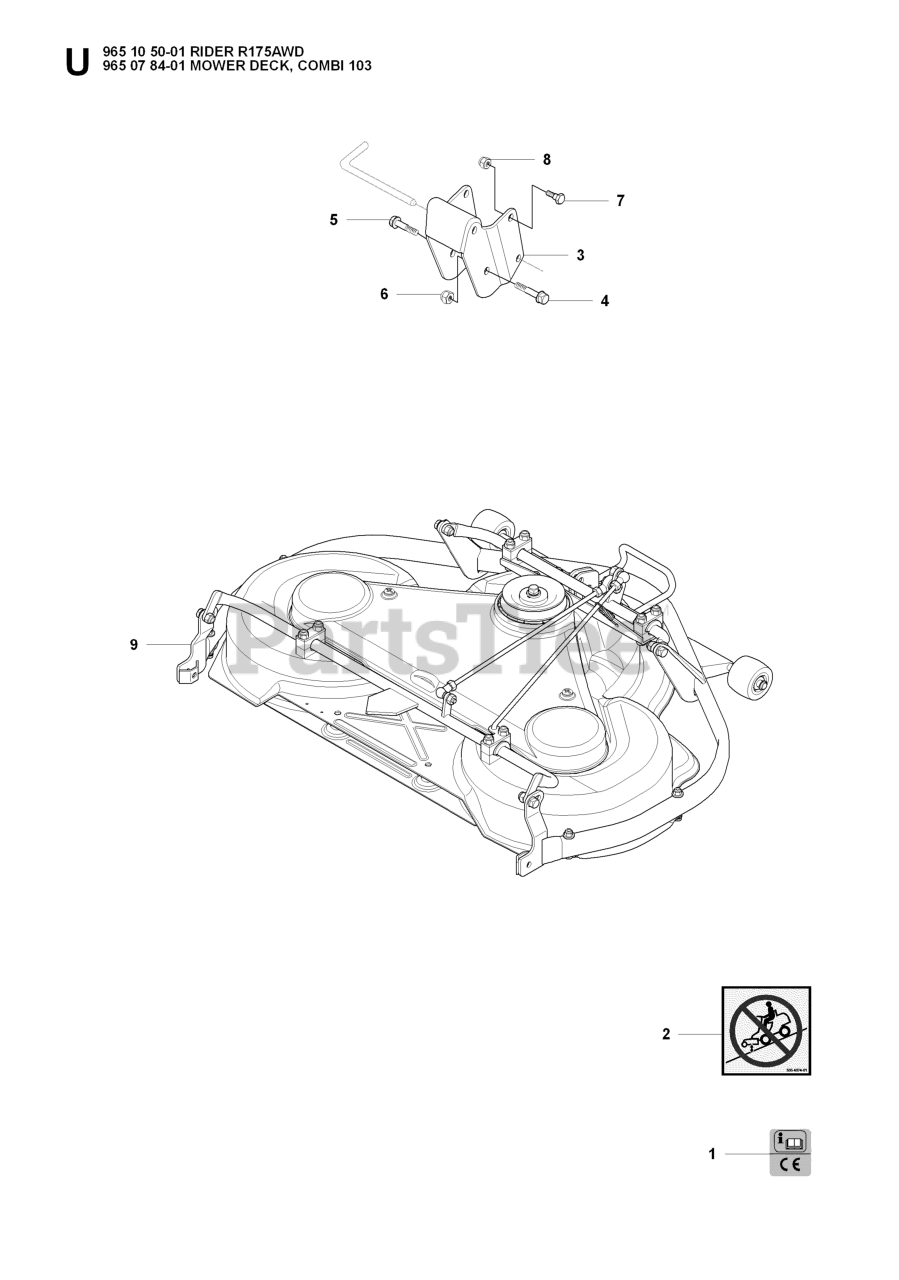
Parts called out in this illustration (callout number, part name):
5	Hex Head Capscrew, M12 X 1.75 X 30 DIN933ZP
8	LOCKNUT M8
9	DECK COMBI 103
